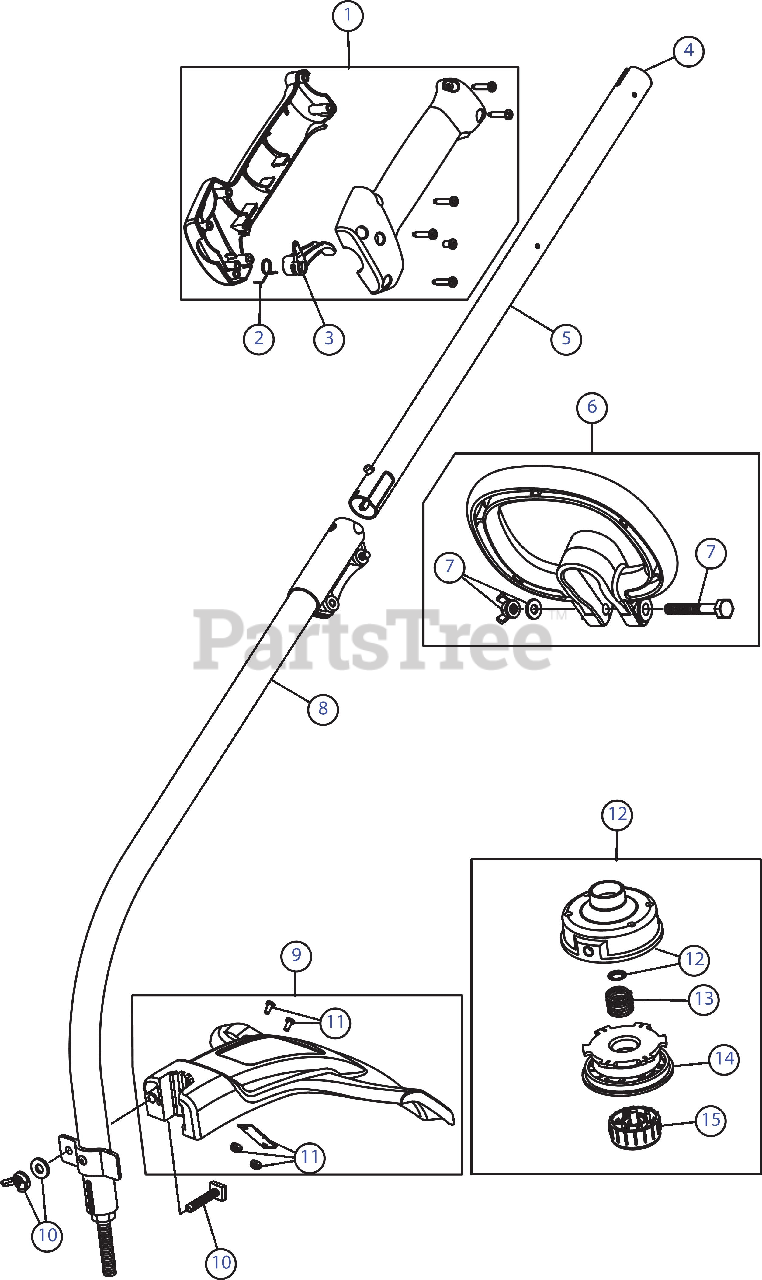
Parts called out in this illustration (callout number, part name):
1	Throttle Housing Assembly (Incl. 2 & 3)
2	Throttle Trigger Spring
3	Throttle Trigger
4	Flexible Drive Shaft
5	Upper Shaft Housing Assembly
6	D-Handle (Incl. 7)
7	D-Handle Hardware
8	Lower Shaft Housing Assembly
9	Shield Assembly (Incl. 10 & 11)
10	Shield Mounting Hardware
11	Blade Assembly
12	Outer Spool Assembly (with Retainer)
14	Inner Reel
15	Bump Head Knob Assembly
